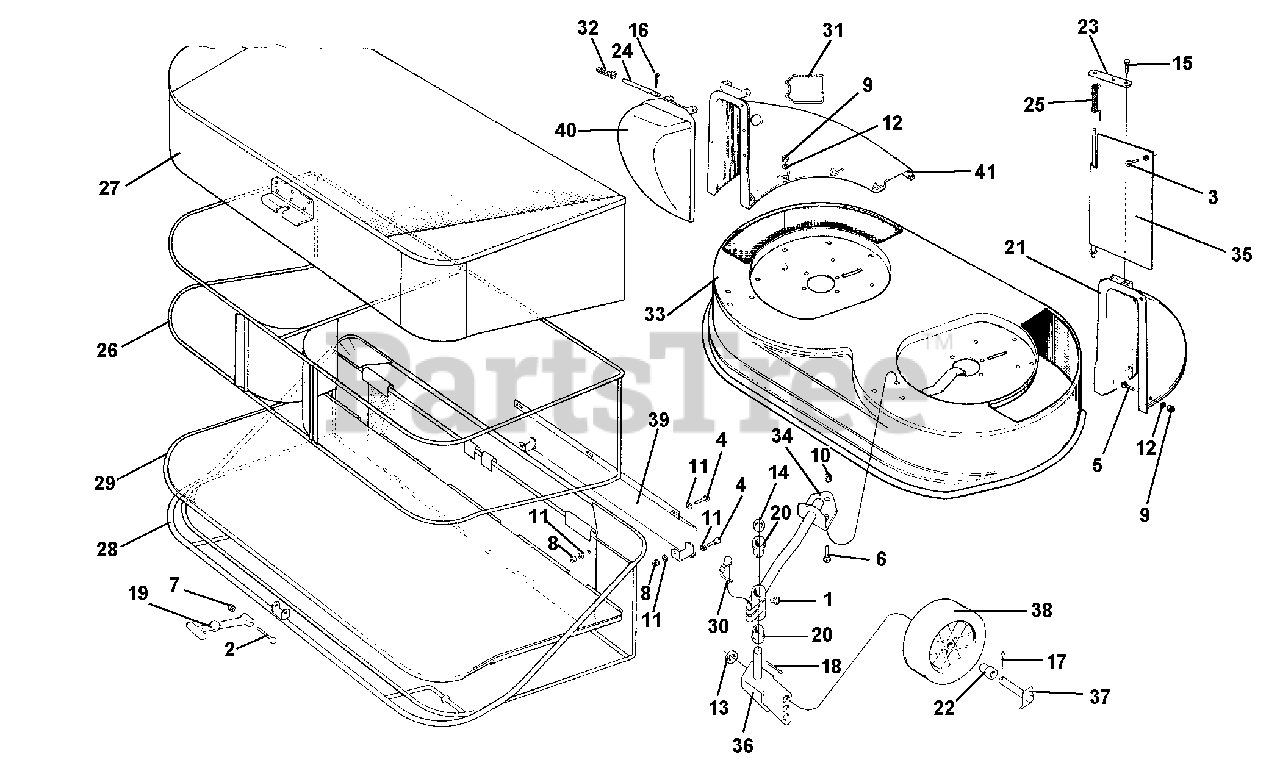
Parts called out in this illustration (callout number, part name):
1	LUBRICATOR M10
2	SCREW TE M4 X 35
3	SCREW TE M6 X 14
4	SCREW M5 X 16
5	SCREW M6 X 20
6	SCREW TTQ M8 X 20 UNI 5731
8	NUT, SELF LOCKING M5 STAND.
9	NUT, SELF LOCKING M6
10	NUT, SELF LOCKING M8
11	WASHER, FLAT 5.3
12	WASHER, FLAT 6.4
13	WASHER, FLAT 17 UNI 1733
14	WASHER, FLAT 21 UNI 1736
15	SCREW 6.3 X 19
16	COTTER PIN A 3 X 15 UNI 1336 AC.
17	PIN, COTTER 4 X 25
18	PIN, COTTER A 4 X 30 UNI 1336
19	HANDLE RUBBER
21	L.H. CONVEYOR
22	SMALL WHEEL BUSH
28	BAG BOTTOM FRAME
32	DEFLECTOR SPRING
33	LAWN MOWER CRANKCASE
34	SMALL WHEEL SUPPORT
37	SMALL WHEEL PIN
38	SMALL WHEEL
39	REAR PROTECTION
